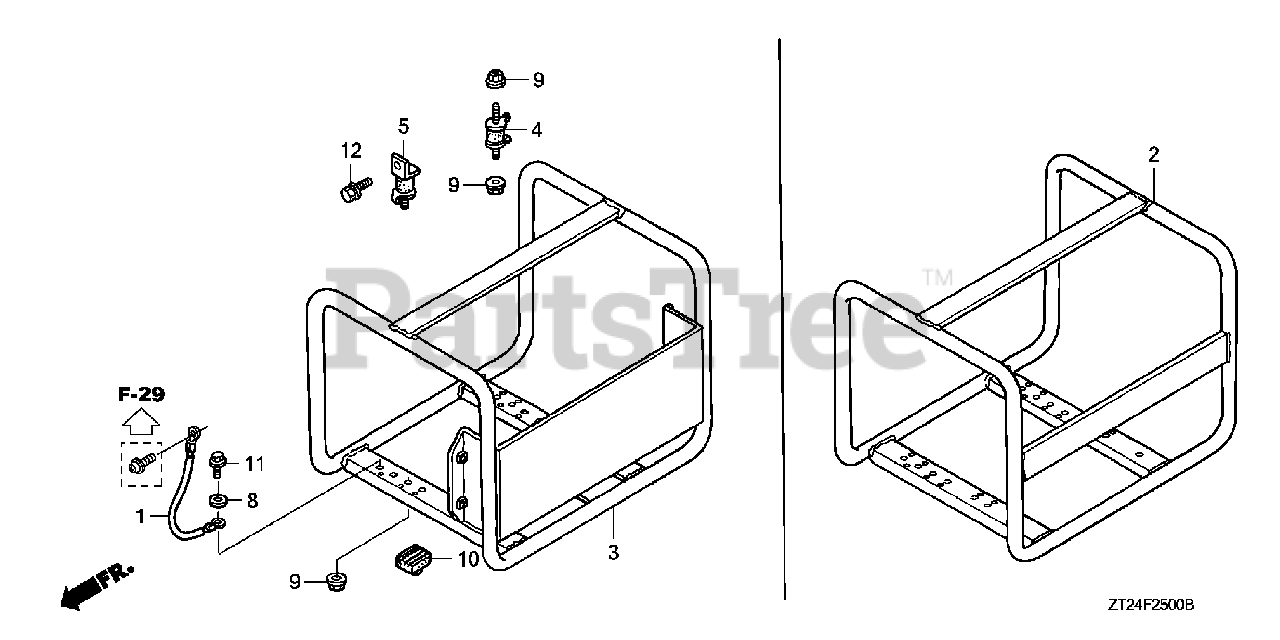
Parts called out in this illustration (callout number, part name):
1	CABLE, GROUND
3	FRAME *NH105* (MAT BLACK)
4	RUBBER, ENGINE MOUNTING
5	RUBBER, ALTERNATOR MOUNTING
8	WASHER, LOCK (6MM)
9	NUT, FLANGE (8MM)
10	RUBBER D, STAND STOPPER
11	BOLT, FLANGE (6X10)
12	BOLT, FLANGE (8X20)
